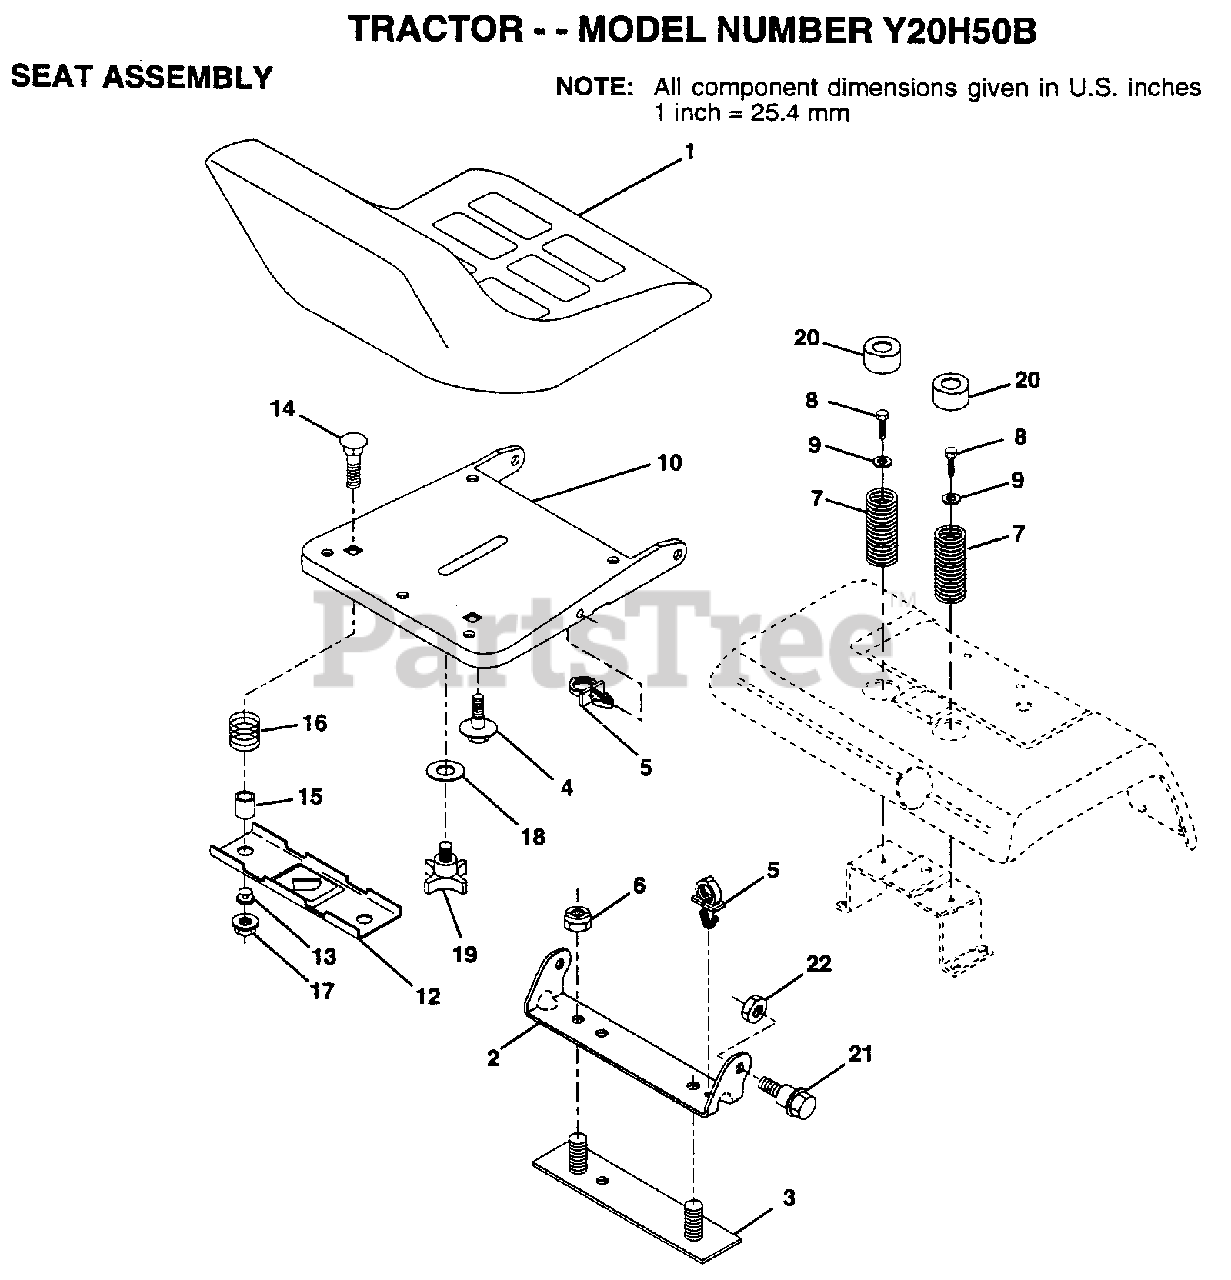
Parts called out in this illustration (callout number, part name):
2	BRACKET PVT SEAT
3	STRAP ASM FENDER
4	BOLT,SHOULDER
5	CLIP.PUSH-IN.HING
7	SPRING COMPRESSIO
8	SCREW LT
9	WASHER
12	BRKT SWITCH
13	BUSHING
15	SPACER SPLIT
16	SPRING COMPRESSED
17	NUT.LOCK.1/4.LGE.FLG.GR.5
18	WASHER
20	CAP SPRING
21	BOLT.SHLD.5/16-18
